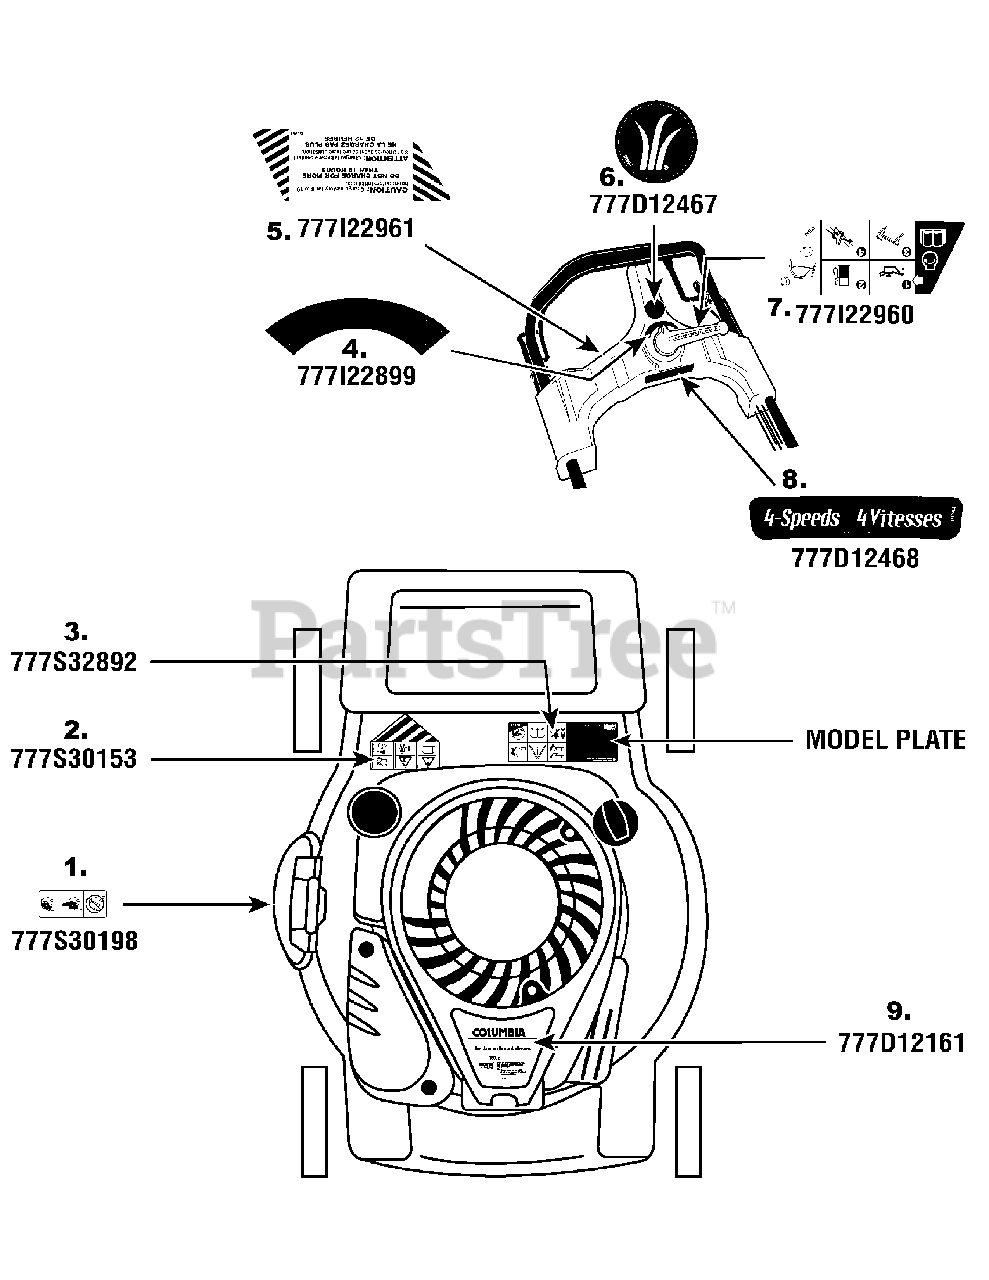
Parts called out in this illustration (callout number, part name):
2	LABEL-DANGER CHUTE
3	LABEL-MWR DNGR
4	LABEL-MOWER XP HANDLE SELECT
5	LABEL-MWR HNDL BATTERY
6	LABEL-MWR HNDL SPRIG
7	LABEL-MWR HNDL INST
8	LABEL-HNDL 4 SPEED
9	LABEL-ENG SHROUD COLUMBIA
